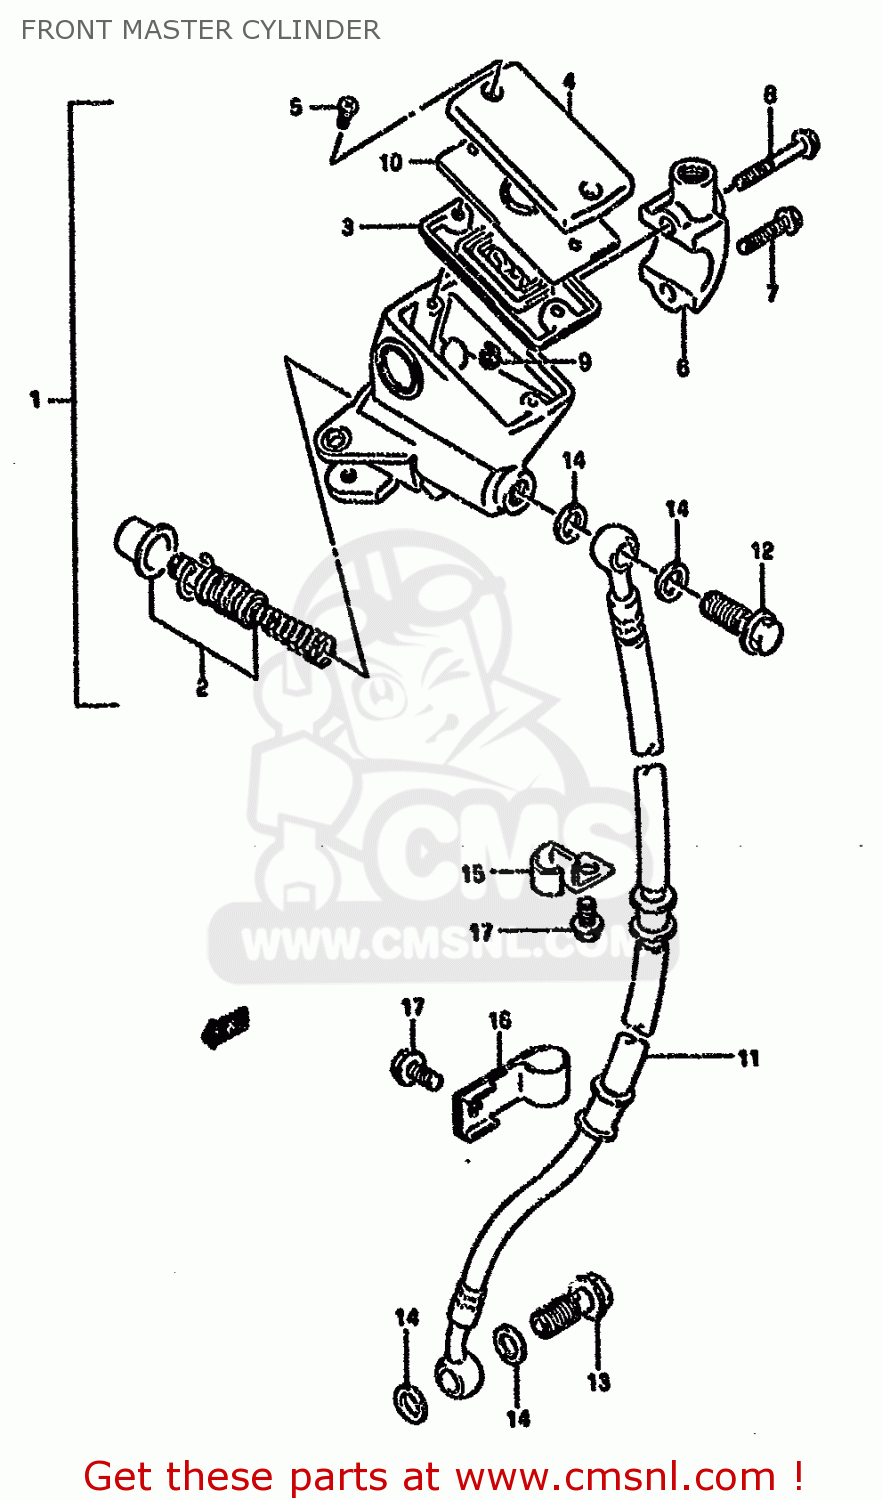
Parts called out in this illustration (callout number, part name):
1	CYLINDER ASSY,FR MASTER
2	CUP SET,MASTER CYLINDER
3	4-1
4	CAP
5	SCREW
6	HOLDER
7	BOLT(6X25)
8	BOLT(6X38)
9	PROTECTOR
10	PLATE,DIAPHRAGM
11	HOSE,FR BRAKE,R
12	BOLT UNION
13	BOLT UNION
14	WASHER(10X15X1.5)
15	CLAMP,FR BRAKE HOSE
16	CLAMP,FRONT BRAKE NO.2
17	BOLT
